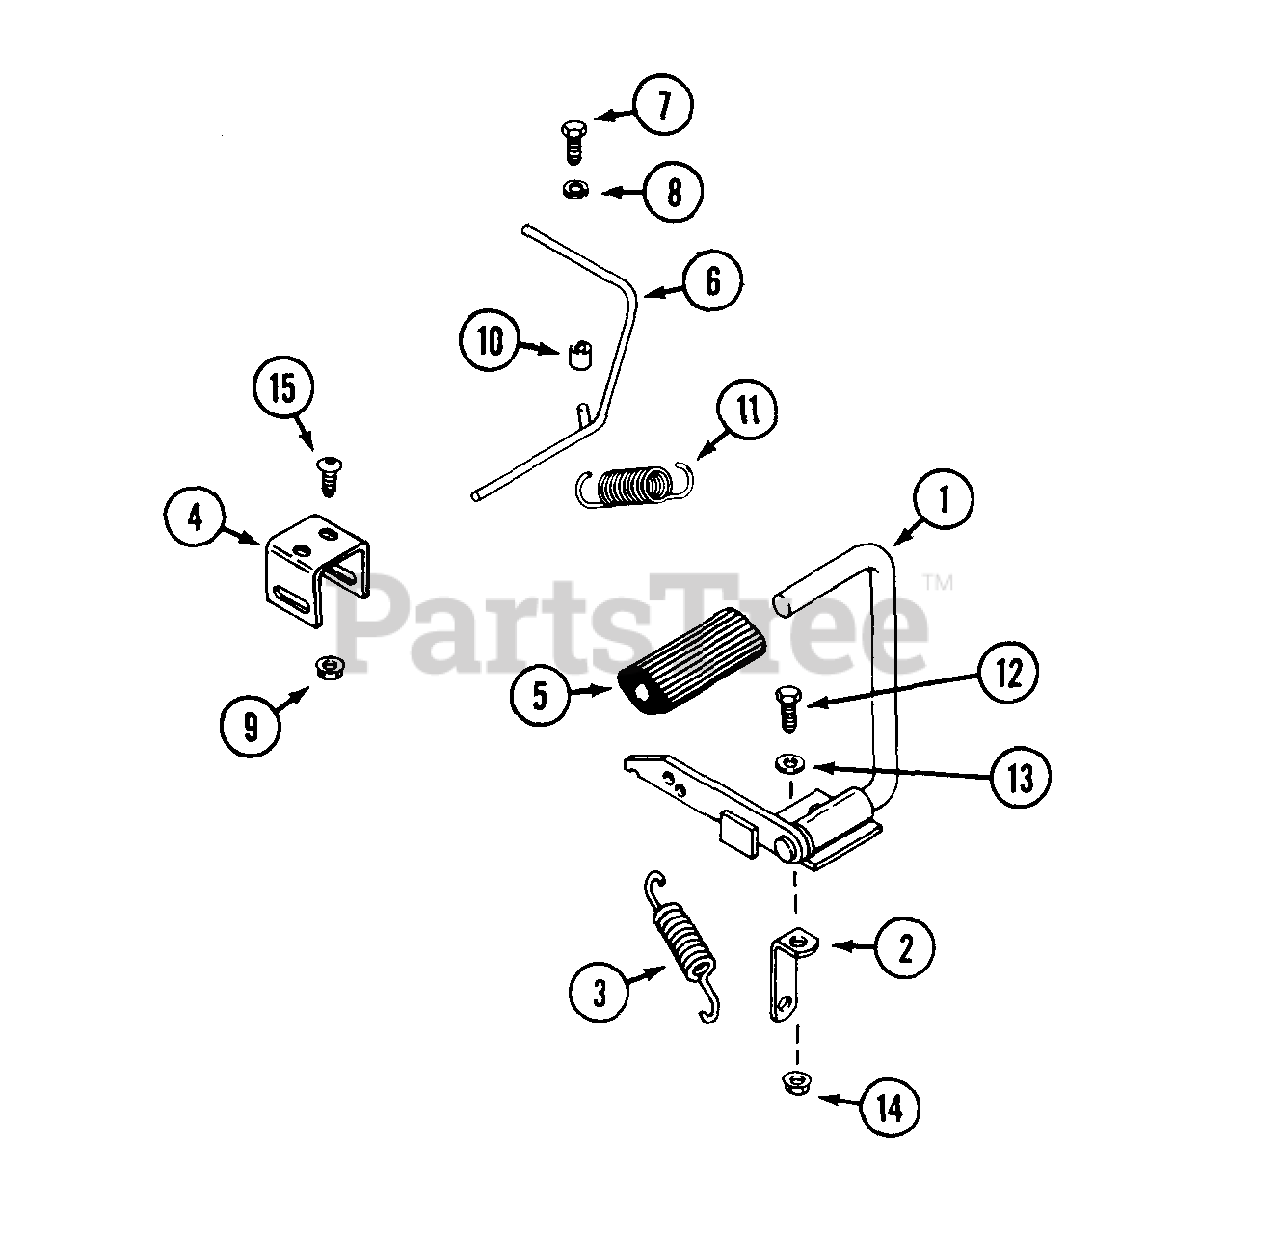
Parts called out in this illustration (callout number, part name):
1	PEDAL - parking brake
2	TAB - spring mount
3	SPRING - brake return
4	BRACKET - brack lock
5	PAD - brake pedal
6	LEVER - brake lock
7	SCREW - 5/16" - 18 x 5/8" allen head
8	LOCKWASHER - 5/16"
9	NUT - 1/4" - 20 flange lock
11	SPRING - return, lock lever
12	BOLT - 5/16" - 18 x 1"
13	WASHER - 5/16"
14	NUT - 5/16" - 18 flange lock
15	SCREW - 1/4" - 20 x 1/2" allen head
